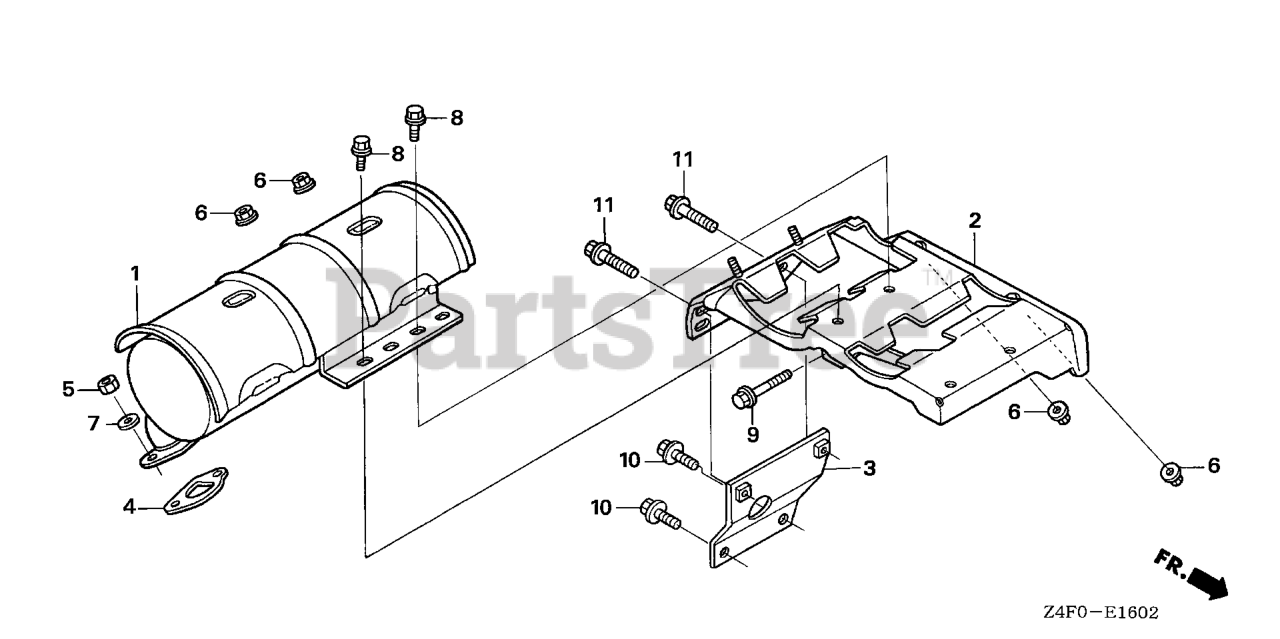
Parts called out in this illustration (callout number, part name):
2	STAY, MUFFLER
4	GASKET, MUFFLER
5	NUT, HEX. (8MM)
6	NUT, FLANGE (6MM)
7	WASHER, PLAIN (8MM)
8	BOLT, FLANGE (6X16) Use from Engine SN 2056820.
9	BOLT, FLANGE (6X25)
11	BOLT, FLANGE (8X20) Use up to Engine SN 1609606.
